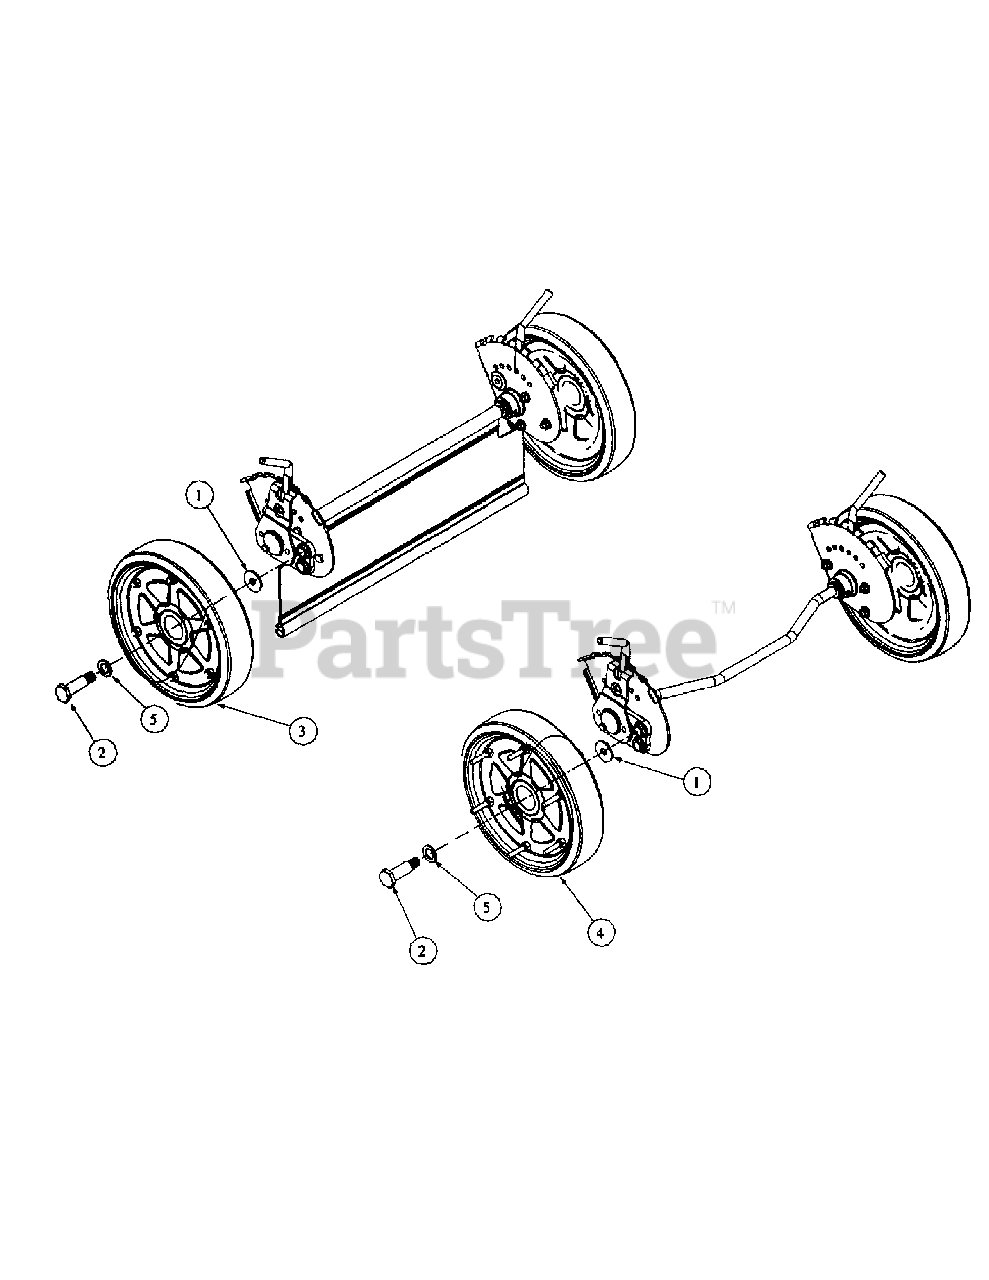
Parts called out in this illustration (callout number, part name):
1	Washer, 1/2 x 1 Shim
2	Shoulder Screw, 58 x 1.48, 1/2-20
3	Wheel, 9 x 2 .125 With drive Gear
4	Wheel, 9 x 2 .125 With drive Gear
5	Washer, .625 x .875 x .031
